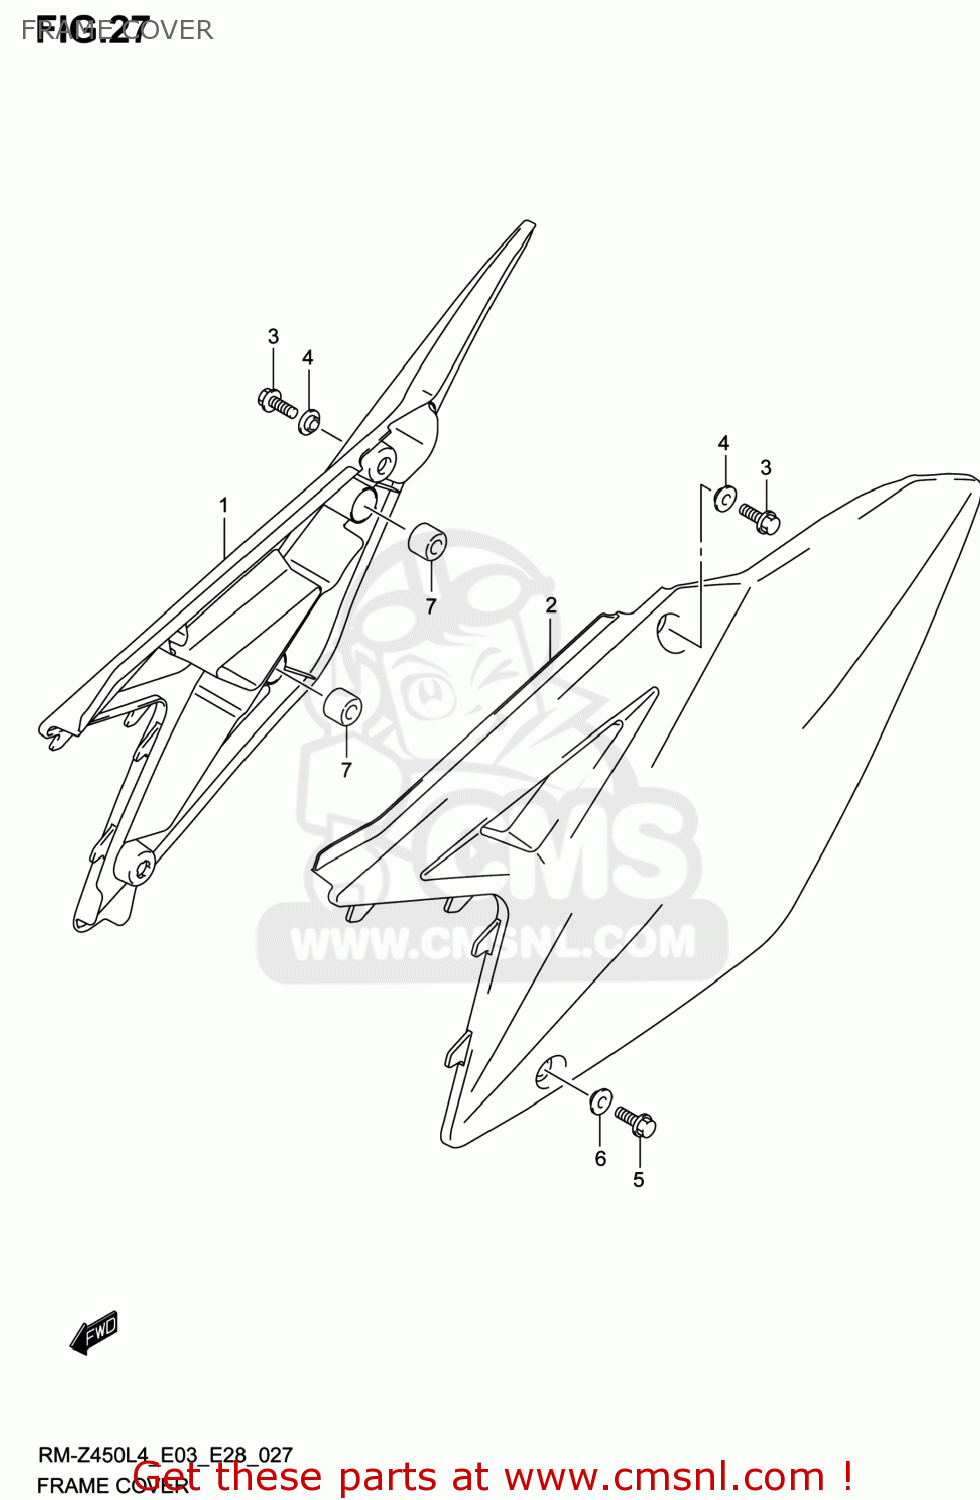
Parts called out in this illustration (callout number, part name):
1	COVER,FRAME R(YELLOW)
2	COVER,FRAME,L(YELLOW)
3	BOLT
4	WASHER,FRAME COVER & SEAT
5	BOLT
6	WASHER,FRAME COVER & SEAT
7	CUSHION
